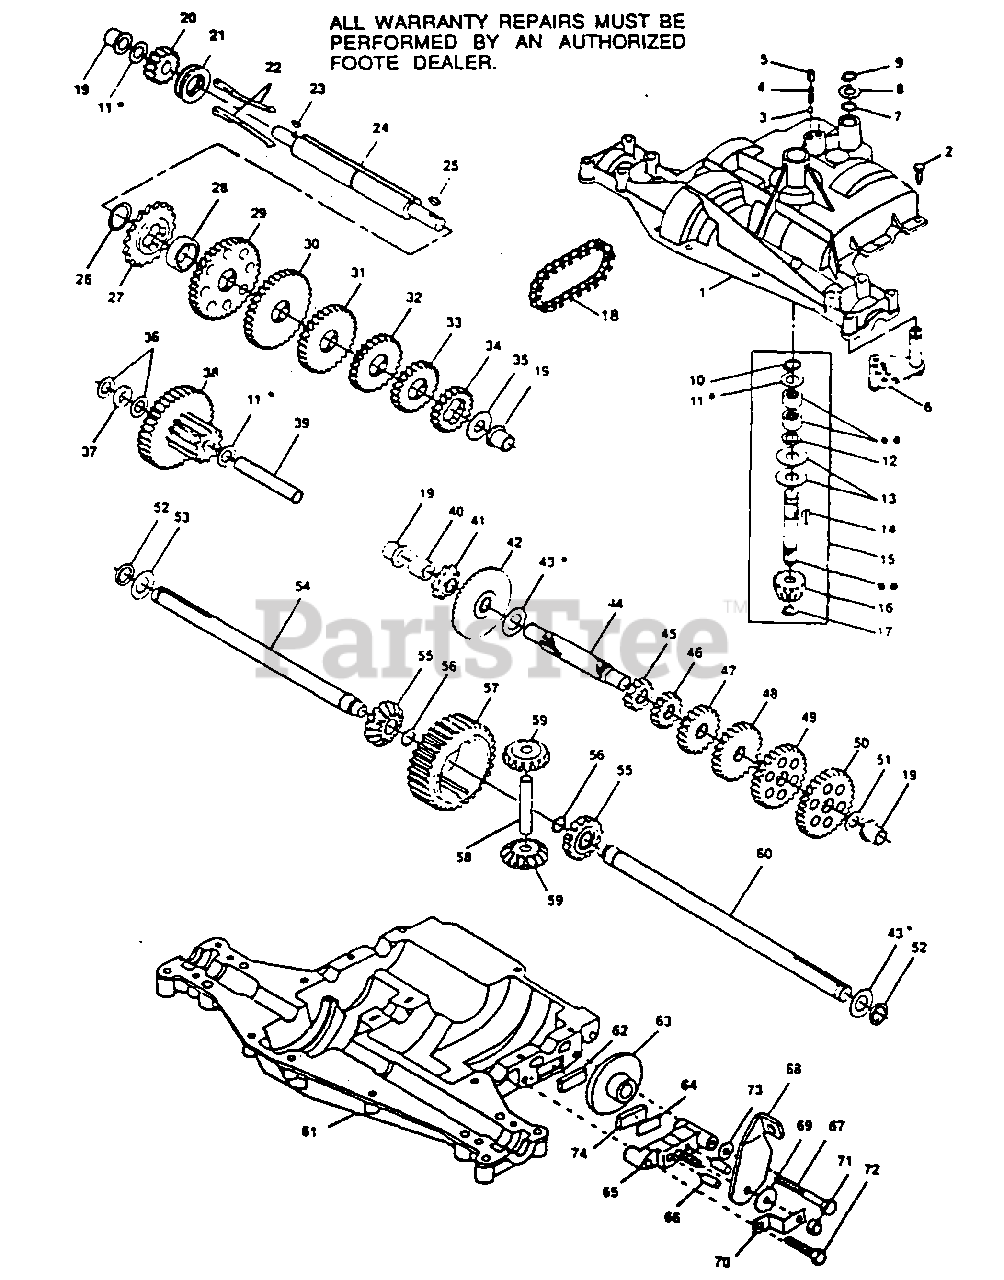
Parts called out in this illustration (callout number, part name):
1	Housing, Upper (Dana part number)
2	Screw, Tapping, 1/4-20 x .734 Lg. (Dana part number)
3	Ball, Detent (Dana part number)
4	Spring, Detent (Dana part number)
5	Screw, Set (Dana part number)
6	Assy., Shifter (Dana part number)
7	O-Ring (Dana part number)
8	Washer, Plain, .505 x .942 x .006 (Dana part number)
8	Washer, Plain, .505 x .942 x .010 (Dana part number)
8	Washer, Plain, .505 x .942 x .015 (Dana part number)
8	Washer, Plain, .505 x .942 x .020 (Dana part number)
8	Washer, Plain, .505 x .942 x .026 (Dana part number)
8	Washer, Plain, .505 x .942 x .030 (Dana part number)
8	Washer, Plain, .505 x .942 x .040 (Dana part number)
9	Ring, Retaining (Dana part number)
10	Ring, Retaining (Dana part number)
11	Washer, Plain, .632 x 1.00 x .010 (Dana part number)
11	Washer, Plain, .632 x 1.00 x .020 (Dana part number)
11	Plain Washer .632 x 1.00 x .026 (Dana part number)
11	Washer, Plain, .632 x 1.00 x .031 (Dana part number)
11	Washer, Plain, .632 x 1.00 x .036 (Dana part number)
11	Washer, Plain, .632 x 1.00 x .041 (Dana part number)
11	Washer, Plain, .632 x 1.00 x .046 (Dana part number)
11	Washer, Plain, .632 x 1.00 x .050 (Dana part number)
11	Washer, Plain, .632 x 1.00 x .060 (Dana part number)
11	Washer, Plain, .632 x 1.00 x .082 (Dana part number)
12	O-Ring (Dana part number)
13	Washer, Plain, .632 x 1.38 x .046
14	Key, Woodruff, #9
15	Ass'y., Kit, Input Shaft (Dana part number)
16	Pinion, Bevel, 14T. (Dana part number)
17	Ring, Retaining (Dana part number)
18	Chain, 24 Pitches (Dana part number)
19	Bearing, Flange (Dana part number)
20	Gear, Spur, 14T.
21	Collar, Clutch (Dana part number)
22	Key, Clutch (Dana part number)
23	Key, Woodruff
24	Shaft, Intermediate (Dana part number)
25	Key, Woodruff, #61 (Dana part number)
26	Ring, Retaining (Dana part number)
27	Sprocket, 18T. (Dana part number)
28	Spacer (Dana part number)
29	Gear, Spur, 37T.
30	Gear, Spur, 35T.
31	Gear, Spur, 30T. (Dana part number)
32	Gear, Spur, 25T.
33	Gear, Spur, 22T. (Dana part number)
34	Gear, Spur, 19T. (Dana part number)
35	Washer, Plain, .640 x 1.37 x .061 (Dana part number)
36	Plain Washer .632 x 1.00 x .026 (Dana part number)
37	Spacer, .630 x 1.00 x .169 (Dana part number)
38	Ass'y., Gear, Comb., 12T. & 35T. (Dana part number)
39	Shaft, Idler (Dana part number)
40	Spacer, .635 x.875 x .755 (Dana part number)
41	Sprocket, 9T. (Dana part number)
42	Gear, Bevel, 42T. (Dana part number)
43	Washer, Plain, .758 x 1.12 x .010 (Dana part number)
43	Washer, Plain, .758 x 1.12 x .015 (Dana part number)
43	Washer, Plain, .758 x 1.12 x .020 (Dana part number)
43	Washer, Plain, .758 x 1.12 x .025 (Dana part number)
43	Washer, Plain, .758 x 1.25 x .020 (Dana part number)
43	Washer, Plain, .758 x 1.25 x .025 (Dana part number)
43	Washer, Plain, .758 x 1.25 x .031 (Dana part number)
43	Washer, Plain, .758 x 1.25 x .035(Dana part number)
43	Washer, Plain, .758 x 1.25 x .040(Dana part number)
43	Washer, Plain, .758 x 1.25 x .045 (Dana part number)
43	Washer, Plain, .758 x 1.25 x .050 (Dana part number)
43	Washer, Plain, .758 x 1.25 x .055 (Dana part number)
43	Washer, Plain, .758 x 1.25 x .062 (Dana part number)
44	Shaft, Drive (Dana part number)
45	Gear, Spur, 12T. (Dana part number)
46	Gear, Spur, 15T. (Dana part number)
47	Gear, Spur, 20T. (Dana part number)
48	Gear, Spur, 25T. (Dana part number)
49	Gear, Spur, 28T. (Dana part number)
50	Gear, Spur, 31T. (Dana part number)
51	Washer, Plain, .632 x 1.00 x .060 (Dana part number)
52	Seal, Felt (Dana part number)
53	Washer, Plain, .758 x 1.25 x .062 (Dana part number)
54	Axle, L.H. (Dana part number)
55	Gear, Miter, 15T.
56	Ring, Retaining (Dana part number)
57	Gear, Spur, 32T. (Dana part number)
58	Shaft, Cross (Dana part number)
59	Gear, Miter, 15T.
60	Axle, R.H. (Dana part number)
61	Housing, Lower (Dana part number)
62	Puck, Friction (Dana part number)
63	Disc, Brake (Dana part number)
64	Spacer (Dana part number)
65	Jaw, Brake (Dana part number)
66	Pin, Dowel (Dana part number)
67	Screw, Tapping, 5/16-18 x 2.25 Lg. (Dana part number)
68	Lever, Actuating
69	Washer, Plain, ..321 x 1.00 x .055
70	Bracket, Anti-Rotation (Dana part number)
71	Nut, Lock, 5/16-24 (Dana part number)
72	Screw, Tapping, 5/16-18 x 1.44 Lg. (Dana part number)
73	Washer, Plain, .343 x .81 x .059
74	Puck, Friction (Dana part number)
75	Grease (Dana part number)
